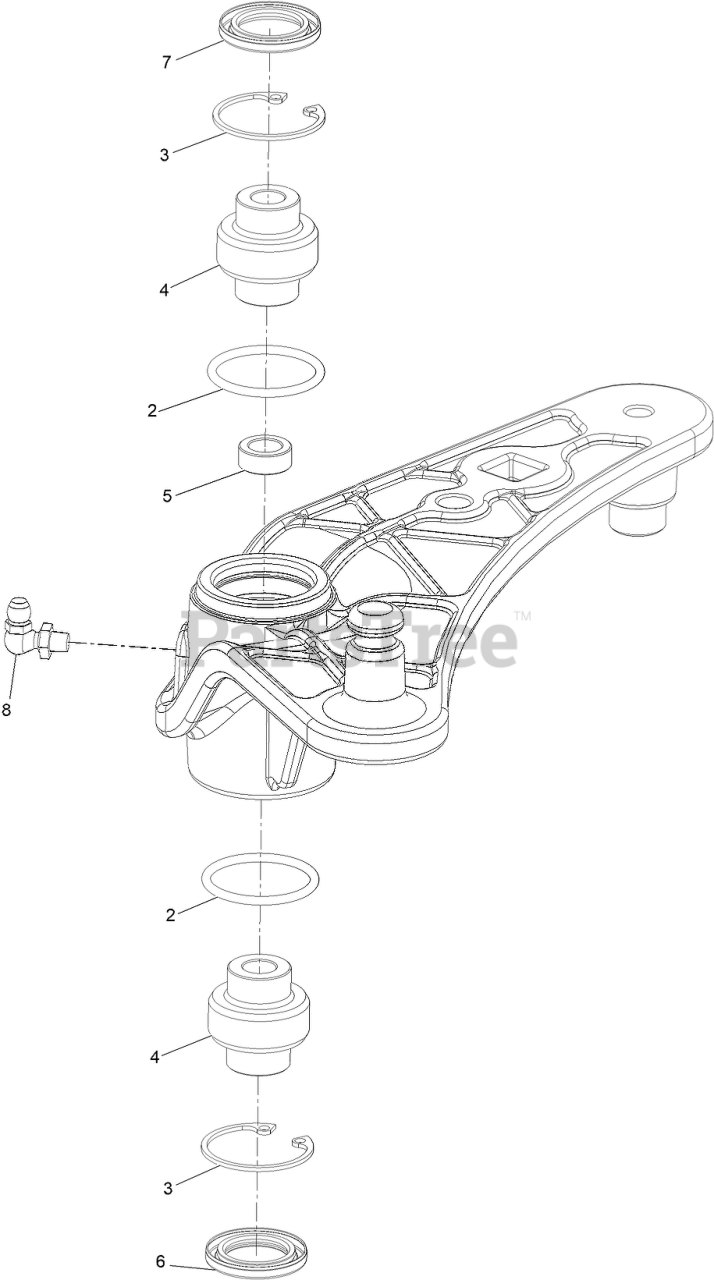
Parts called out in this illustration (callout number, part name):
3	RING-SNAP
4	BEARING-SPHERICAL
6	SEAL-LIP, DOUBLE
7	SEAL-LIP, SINGLE
8	FITTING-GREASE, 90 DEG
